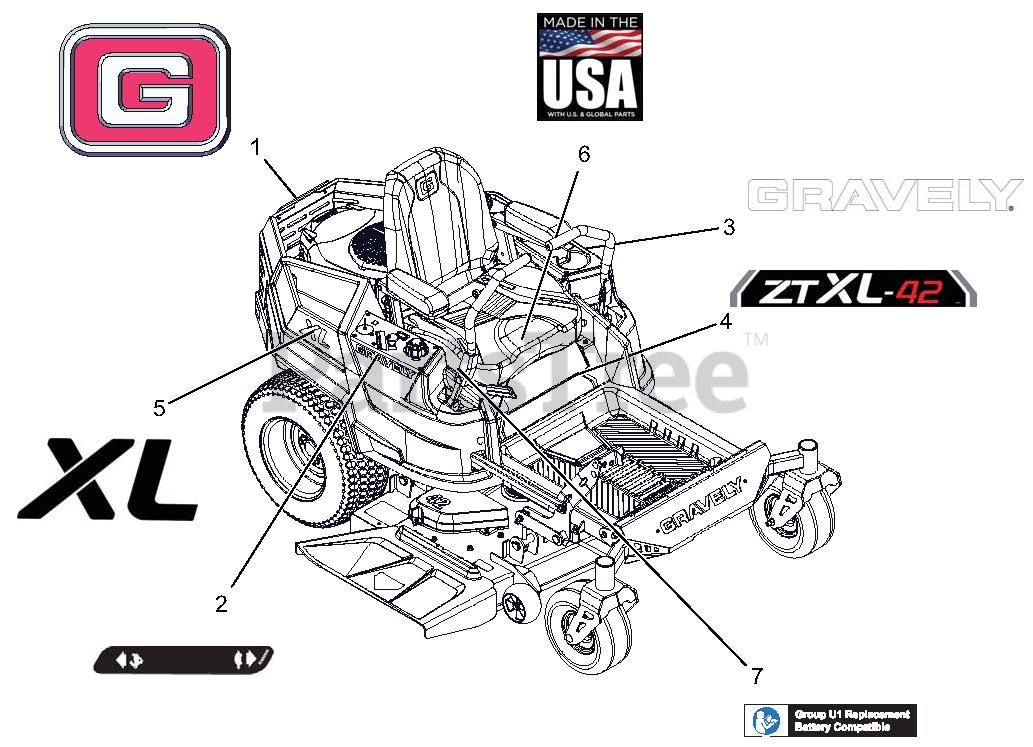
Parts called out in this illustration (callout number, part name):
1	DECAL, GRAVELY BRAND
2	DECAL, DASH DECAL
3	DECAL, 9.5" GRAVELY LOGO
4	DECAL, ZT XL 42"
5	DECAL, "XL"
6	DECAL, MADE IN USA
7	DECAL, U1 BATTERY REPLACEMENT
